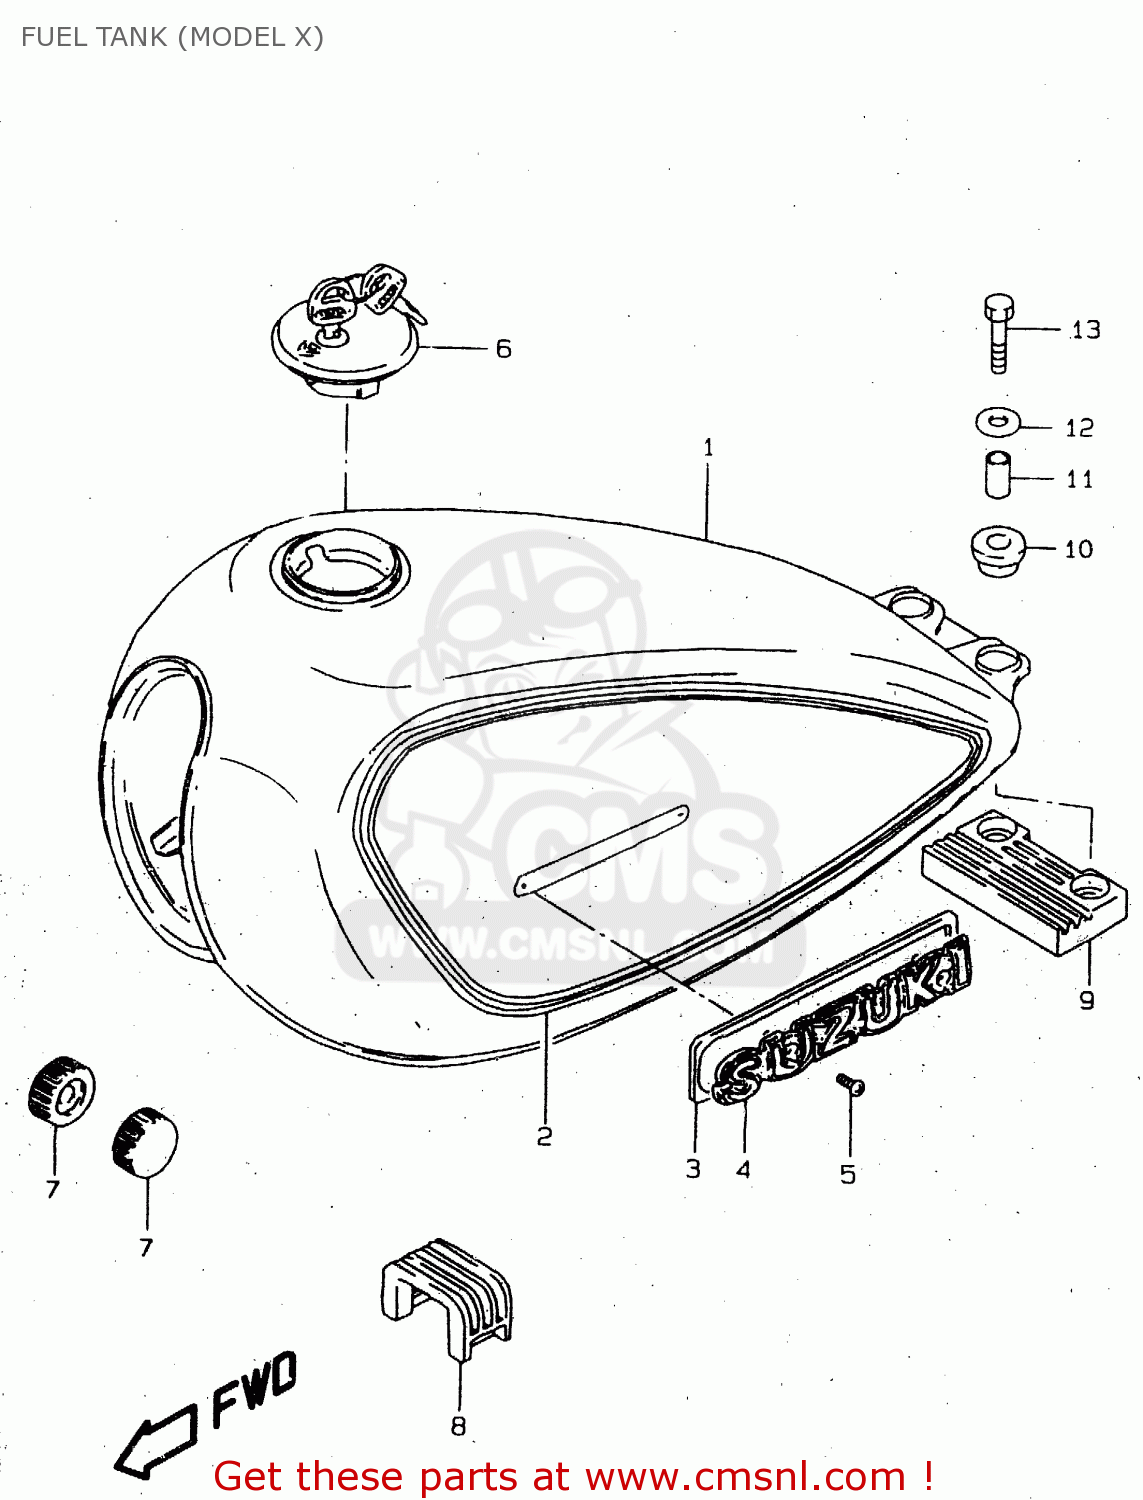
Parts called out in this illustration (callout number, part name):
1	TANK ASSY,FUEL(RED)
2	TAPE SET, FUEL TANK
3	CUSHION
4	EMBLEM,FUEL TANK
5	SCREW
6	CAP SET,FUEL TANK
7	CUSHION
8	CUSHION,TANK UPR FR
9	CUSHION,TANK RR NO.1
10	CUSHION
11	SPACER(6.5X10.5X22.5)
12	WASHER(6.5X22X1.6)
13	BOLT(6X35)
